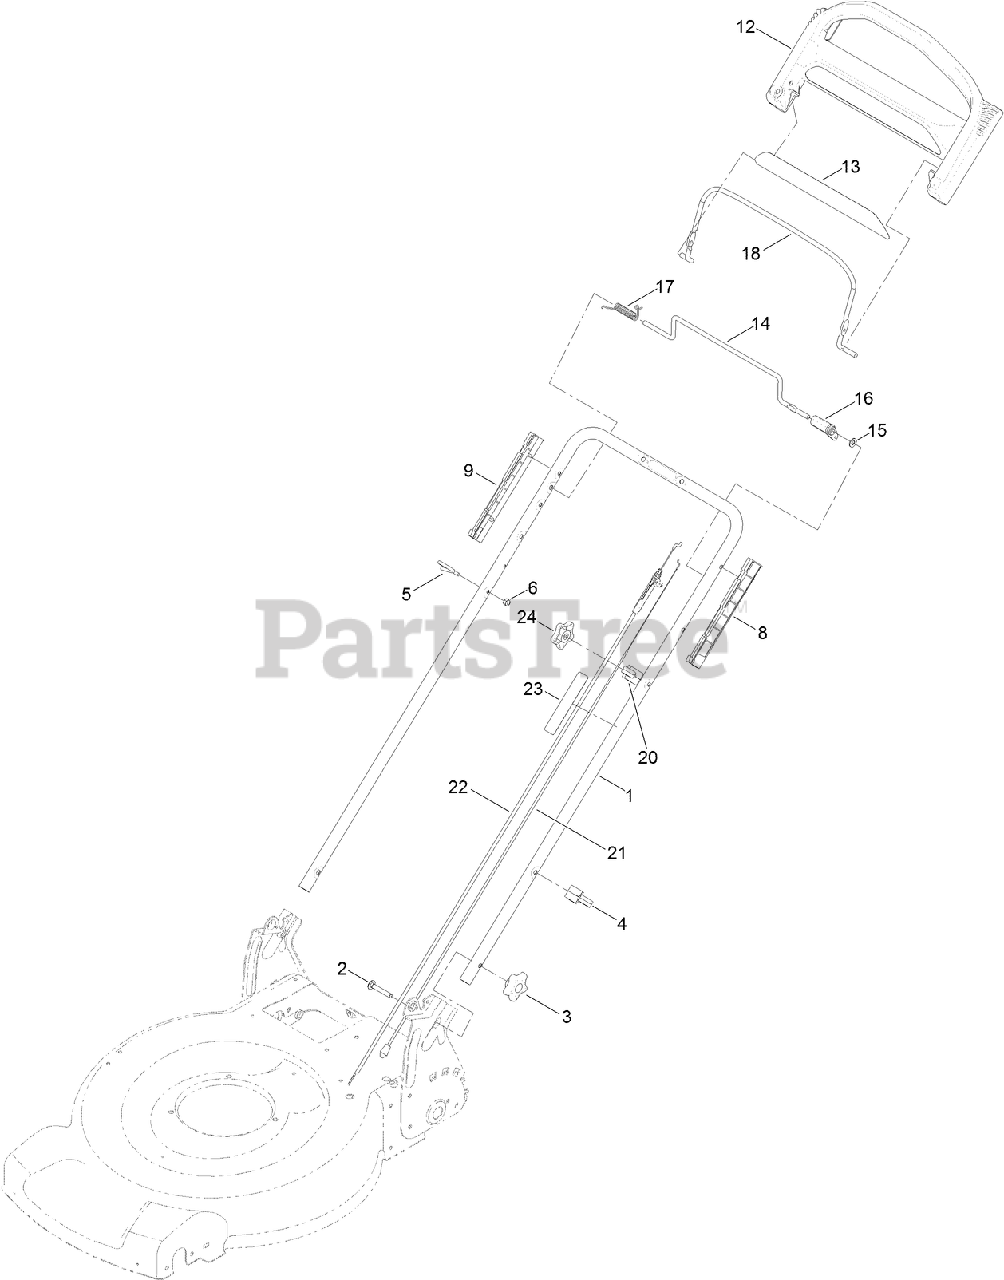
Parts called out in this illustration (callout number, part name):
2	Screw-CARR
3	KNOB-HANDLE
4	GUIDE-CABLE
5	GUIDE-ROPE
6	NUT-LOCK, NI
8	GUIDE-LH
9	GUIDE-RH
12	HANDLE-CONTROL
14	BAR-CONTROL, TRACTION
15	WASHER-PLAIN
16	LEVER-TRACTION
17	Spring-Torsion
18	Bail-Brake
20	ANCHOR-CABLE
21	CABLE-TRACTION
22	CABLE-BRAKE
23	DECAL-TRACTION, ADJUST
24	KNOB-HANDLE, LOCKING
